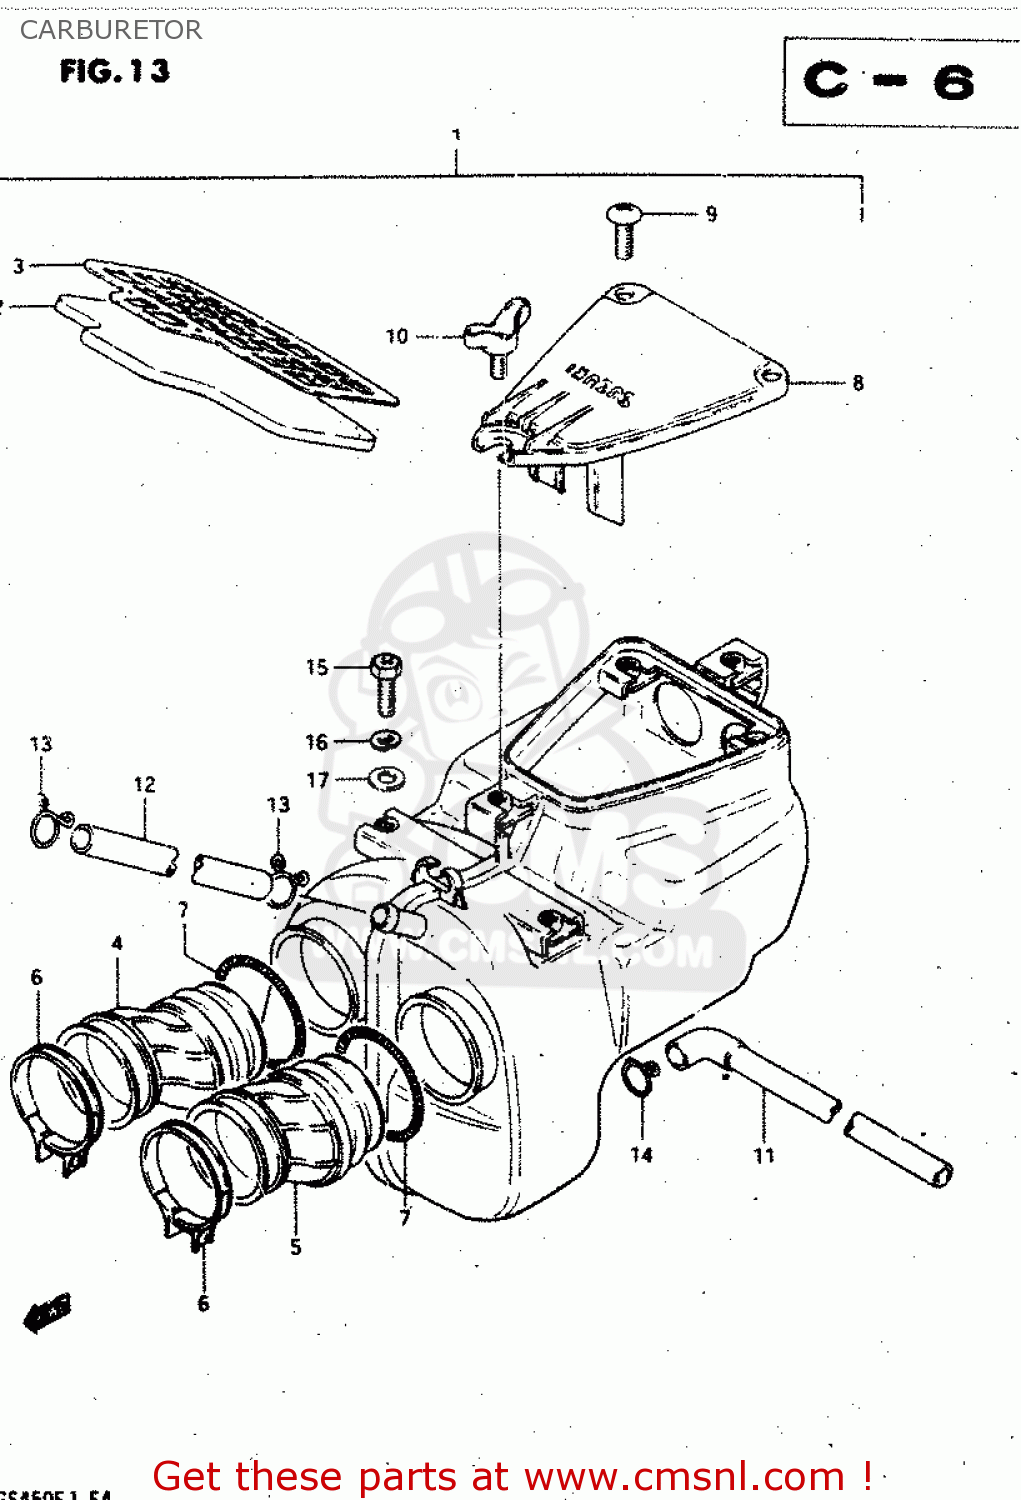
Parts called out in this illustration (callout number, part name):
1	CARBURETOR ASSY, RH
2	CARBURETOR ASSY, LH
3	VALVE,THROTTLE
4	SCREW
5	DIAPHRAGM
6	E RING
7	SPRING,DIAPHRAGM
8	HOLDER,GUIDE
9	RING
10	CLIP
11	WASHER
12	SPRING
13	NEEDLE, JET (4C3-3)
14	E RING
15	GASKET,THROTTLE SHAFT (NAS)
16	SEAL
17	GASKET,FLOAT CHAMBER (NAS)
18	O-RING
19	JET
20	JET, NEEDLE (Y-6)
21	JET,MAIN
22	O-RING
23	SCREW,GUIDE
24	FLOAT
25	VALVE ASSY,NEEDLE
26	PIN,FLOAT
27	GASKET,MAIN JET HOLDER (NAS)
28	FILTER
29	SCREW
30	LOCK WASHER
31	SCREW
32	LOCK WASHER
33	CAP
34	GASKET
35	SCREW
36	LOCK WASHER
37	JET,AIR(1.6)
38	SPRING
39	RING
40	SHAFT ASSEMBLY
41	RING
42	SPRING,THROTTLE SCREW
43	PIN,THROTTLE LEVER
44	NUT
45	SCREW
46	LEVER,STARTER
47	WASHER,STARTER LEVER (4.1X12X0.8)
48	WASHER,STARTER LEVER
49	RING,STARTER LEVER
50	SCREW
51	SPRING,STARTER LEVER S
52	WASHER
53	WASHER
54	SPRING
55	SHAFT ASSEMBLY
56	SHAFT,STARTER
57	SCREW
58	LOCK WASHER
59	SPRING
60	BRACKET,THROTTLE ADJUST
61	BUSHING,THROTTLE ADJUSTER
62	SCREW
63	HOSE 4.5X8X390
64	ARM, STARTER
65	SCREW
66	SCREW 6X12
67	LOCK WASHER
68	HOSE
69	NIPPLE
